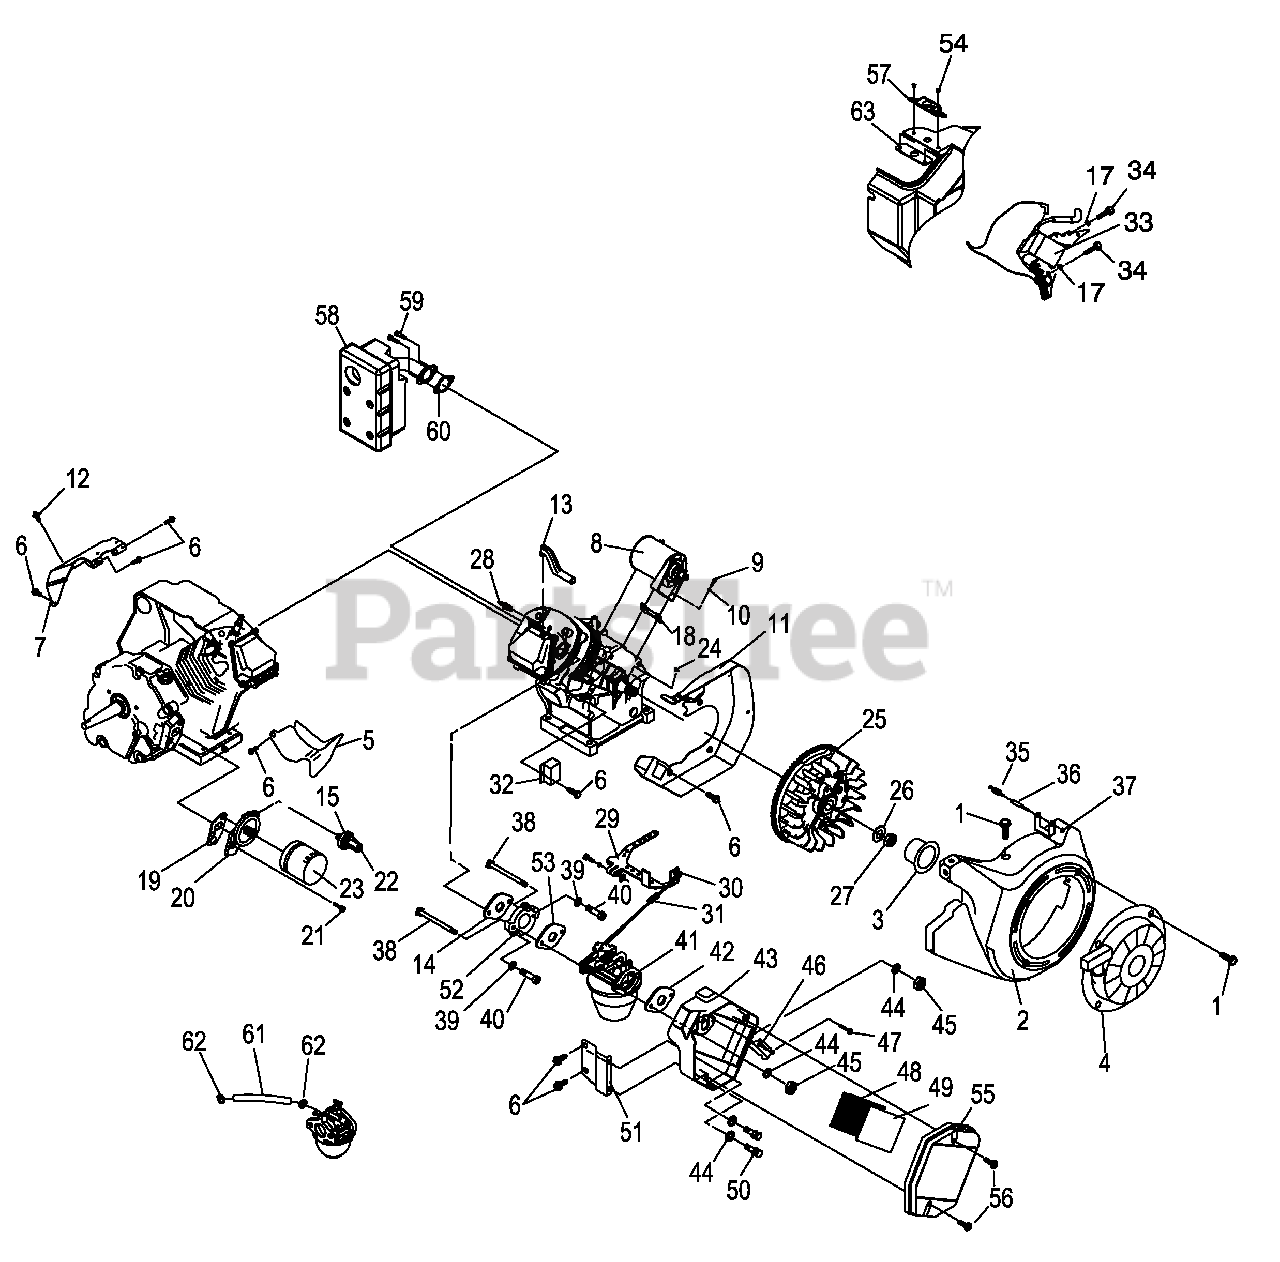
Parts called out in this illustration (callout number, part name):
1	SCREW HHTT M6-1.0 X 8 ZYC
2	ASSEMBLY, BLOWER HOUSING
3	PULLEY STARTER LARGE FRAME
4	RECOIL STARTER LARGE FRAME
5	WRAPPER, BOTTOM 12 HP HS
6	SCREW HHTT M6-1.0 X 10 YELLOW CHROME
7	WRAPPER, TOP REGULAR STEEL
8	ASSEMBLY, STARTER 46
9	SCREW, SHC M8-1.25 X 45 G12.9
10	WASHER, LOCK M8-5/16
11	BACKPLATE, W/ ELECTRIC START
12	SCREW, HHTT M8-1.25 X 16 YELLOW CHROME
13	HOSE, BREATHER GH410 ENGINES
14	GASKET, INTAKE ADAPTER
15	SCREW PPHM #8-32 X 1/4
17	WASHER, LOCK M6-1/4
18	SPACER, ENDFRAME GH 410
19	GASKET,OIL FILTER ADAPTER
20	ADAPTER, OIL FILTER NO TAPPED HOLES
21	SCREW, SHC M8-1.25 X 30 G12.9
22	SWITCH, HOBBS OIL PRESSURE 5PSI
23	FILTER, OIL BLACK 75 LONG
24	KEY, WOODRFF 4 X 19D
25	FLYWHEEL, WITH RING GEAR 27 DEGREE
26	WASHER,BELV-20 X 2.2
27	NUT HEX M20-1.5 G8 YLW CHROME- FLYWHEEL
28	SPARKPLUG, CHAMPION RC14YC
29	ASSEMBLY,GOVERNOR LEVER 12HP
30	ROD, GOVERNOR CONTROL
31	SPRING, ANTI-LASH
32	OIL PRESSURE SHUTDOWN MODULE
33	ASSEMBLY, IGNITION ADV NO DIODE GH410
34	SCREW, HHTT M6-1.0 X 25 ZINC
35	SPRING GOVERNOR 320/360/410
36	BOLT, GOVERNOR ADJUSTMENT M5
37	NUT, HEX LOCK M5-0.8 NYLON INSERT ZINC
38	BOLT, CARBURETOR MOUNTING
40	SCREW, SHC M6-1.0 X 20 G12.9 ZINC PLATED
41	CARBURETOR ASSEMBLY, 410HS
42	GASKET, AIR CLEANER
43	BASE, AIR CLEANER 410 HI FLOW XP PORT
44	WASHER, FLAT M6
45	NUT, HEX LOCK M6-1.0 NYLON INSERT
46	PLATE, SPITBACK
47	SCREW, PLASTITE #8 X .37 LONG
48	ELEMENT, AIR FILTER
49	PRECLEANER, AIR FILTER
50	SCREW, HHC M6-1.0 X 16 W/ LOCK WASHER
51	BRACKET, AIR CLEANER
52	ADAPTER, "K"
53	GASKET, CARBURETOR/MANIFOLD
54	RIVET, 1/8"
55	COVER, AIR CLEANER 13GN
56	BOLT, AIR CLEANER COVER
57	BRACKET, CHOKE CABLE
58	MUFFLER, 410 SIDE-OUT ALUMINIZED
59	SCREW, SHC M8-1.25 X 20 G12.9
60	GASKET, EXHAUST
61	HOSE,1/4" SAE30R7 SETIFLEX 6"
62	CLAMP, HOSE WORM GEAR
63	BACK PLATE
64	GOLF TEE, FUEL LINE PLUG
